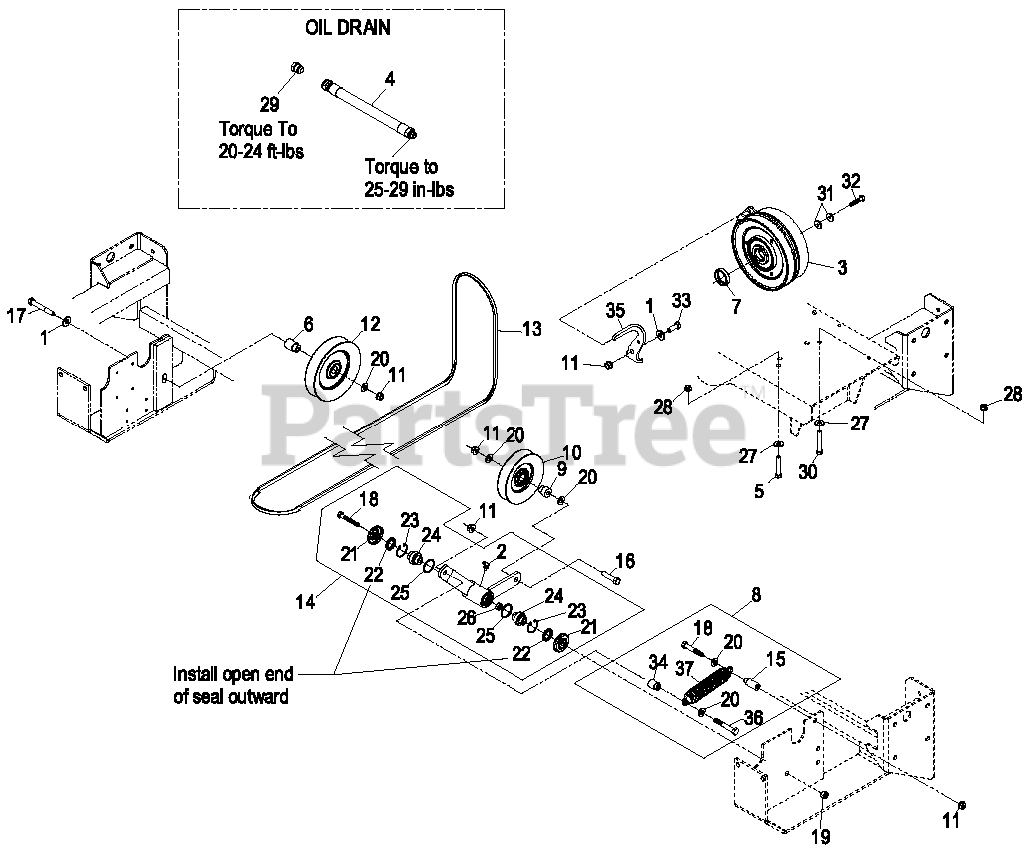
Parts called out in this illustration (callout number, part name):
1	WASHER-BELLEVILLE
2	FITTING-GREASE, 90 DEG
4	ASM,HOSE OIL DRAIN BVG W/
5	SCREW-HH
6	BUSHING-IDLER
7	SPACER,1.63 X1.14 X .18
8	KIT,MULE DRIVE SPRING
9	BUSHING-IDLER
10	PULLEY-IDLER
11	NUT-HHF, WHIZ
12	PULLEY-IDLER
13	BELT-V B 118.75
14	KIT,MULE IDLER LZ
15	SPACER,SPRING MOUNT
16	SCREW-HH
17	SCREW-HH
18	SCREW-HH
19	NUT-LOCK, NI
20	WASHER-FLAT
21	GUARD-TOP
22	SEAL-LIP, SINGLE
23	RING-SNAP
24	BEARING-SPHERICAL
27	WASHER-SPRING
30	SCREW-HH
31	WASHER-SPRING
32	SCREW-HH
33	SCREW-HH
34	BUSHING-IDLER
35	ANCHOR,CLUTCH
36	SCREW-HH
